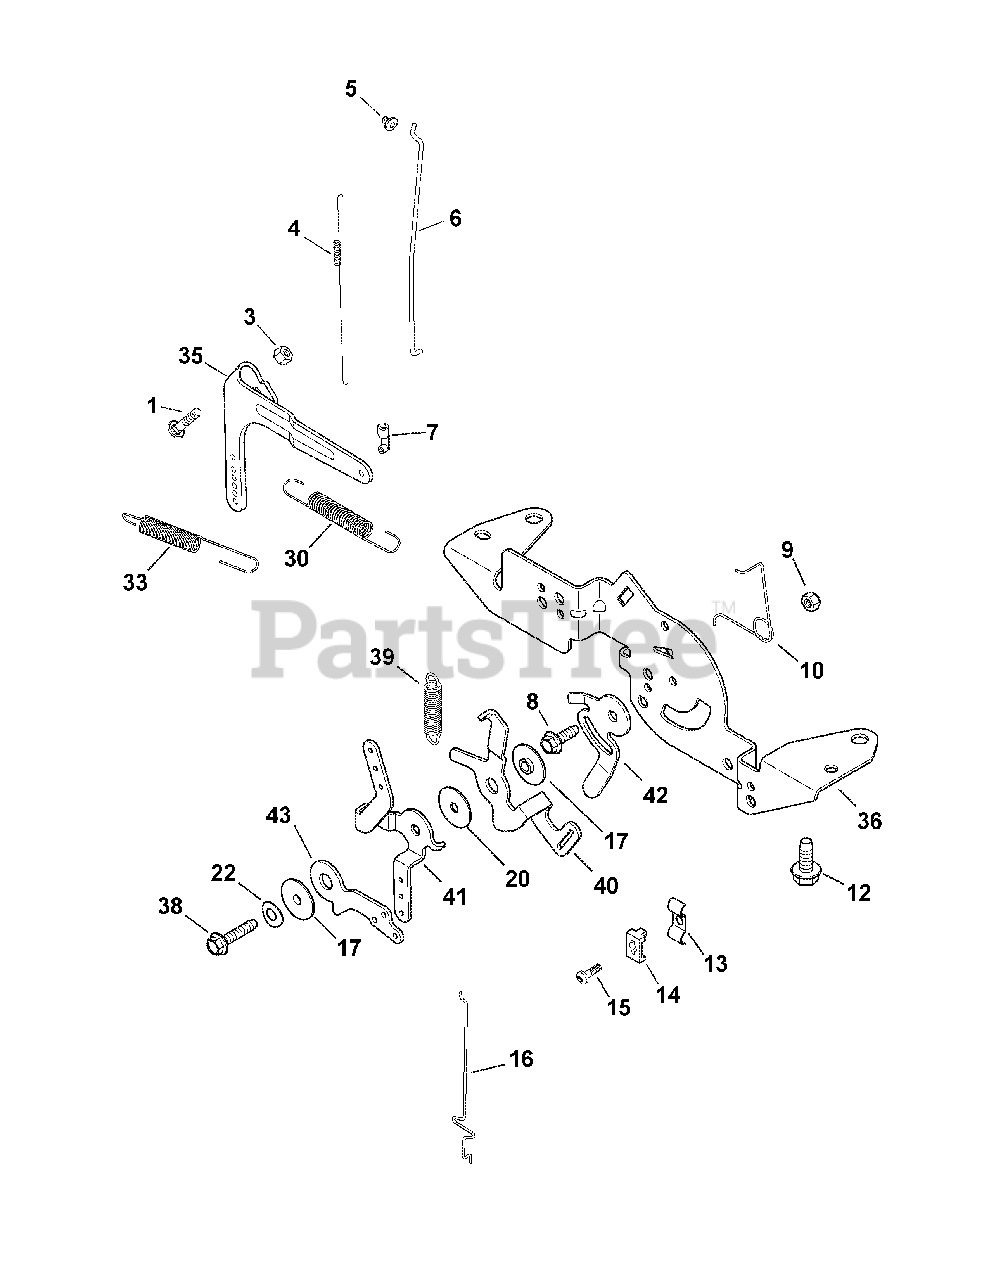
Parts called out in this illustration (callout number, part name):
1	Rd. Hd. Sq. Neck Bolt, M6 x 1.0 x 25
3	Flg. Nut, M6 x 1.0
4	Linkage Spring
5	Linkage Retaining Bushing
6	Throttle Linkage
7	Throttle Linkage Bushing
8	Flg. Thd. Frm. Screw, M5 x 0.8 x 16
9	Lock Nut, M5 x .8
10	Choke Return Spring
12	Flg. Thd. Frm. Screw, M6 x 1.0 x 16
14	Cable Clamp
15	Lbd. Thd. Frm. Screw, M5 x 0.8 x 16
16	Choke Linkage
17	Control Assembly Spacer
20	Flat Washer, 5.5mm
22	Spring Washer, 1.4
30	Governor Spring
33	Governor Spring
35	Governor Lever
36	Control Bracket
38	Thd. Frm. Screw, M5 x 0.8 x 25mm
39	Speed Control Spring
40	Governor Spring Lever
41	Speed Control lever
42	Speed Setting lever
